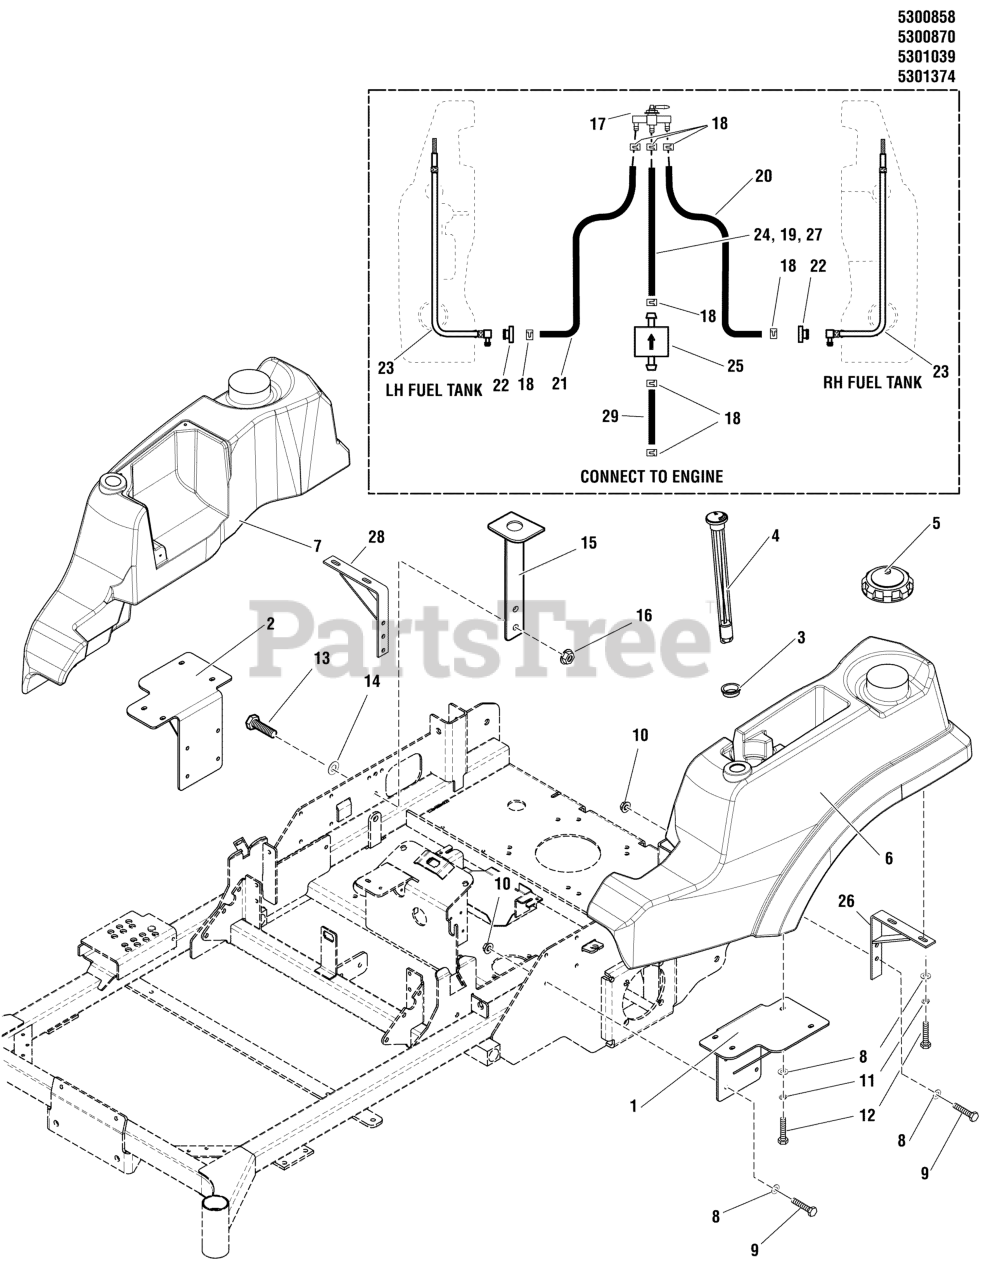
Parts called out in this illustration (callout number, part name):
1	WELD, FUEL MOUNT, RH, SNP 2561 - RED
2	WELD, FUEL MOUNT, LH, SNP 2561 - RED
3	GROMMET, FUEL GAUGE (SV)
4	GAUGE, FUEL, 12
5	CAP, FUEL TANK, 3-1/2 NECK
5	CAP, GASOLINE, VENTED
6	TANK, FUEL, SNAPPER PRO - LH
7	TANK, FUEL, SNAPPER PRO - RH
8	WASHER, 5/16" SAE
9	BOLT, 5/16-18 X 1 GD5 YZ
10	NUT, 5/16-18 HEX NYLOCK FLANGE
11	WASHER, 5/16 LOCK CZ
12	BOLT, 5/16-18 X 3/4 GD5
13	BOLT, 3/8-16 X 1" GD5 CZ
14	WASHER, 3/8 SAE
15	BRACKET, FUEL VALVE, IS3000 - BLK
16	NUT, 3/8-16 HEX NYLOCK FLANGE
17	VALVE, FUEL, STR. OUTLET
18	CLAMP, HOSE, EXTERNAL, 1/2 - RED
19	HOSE, LW PRMTN, 1/4 X 11" FUEL LINE (SV)
20	HOSE, 1/4" FUEL, 21.00"
21	HOSE, 1/4" FUEL, 47.00"
22	BUSHING-FUEL TANK RED RUBBER
23	PICKUP TUBE ASSEMBLY, FUEL LINE (SV)
24	HOSE, 1/4" FUEL, 28.00"
25	FUEL FILTER (SV)
26	WELD, TANK MOUNT, REAR, LH
27	HOSE, LW PRMTN, 1/4 X 32" FUEL LINE (SV)
28	WELD, TANK MOUNT, REAR, RH
29	HOSE, LW PRMTN, 1/4 X 16" FUEL LINE (SV)
